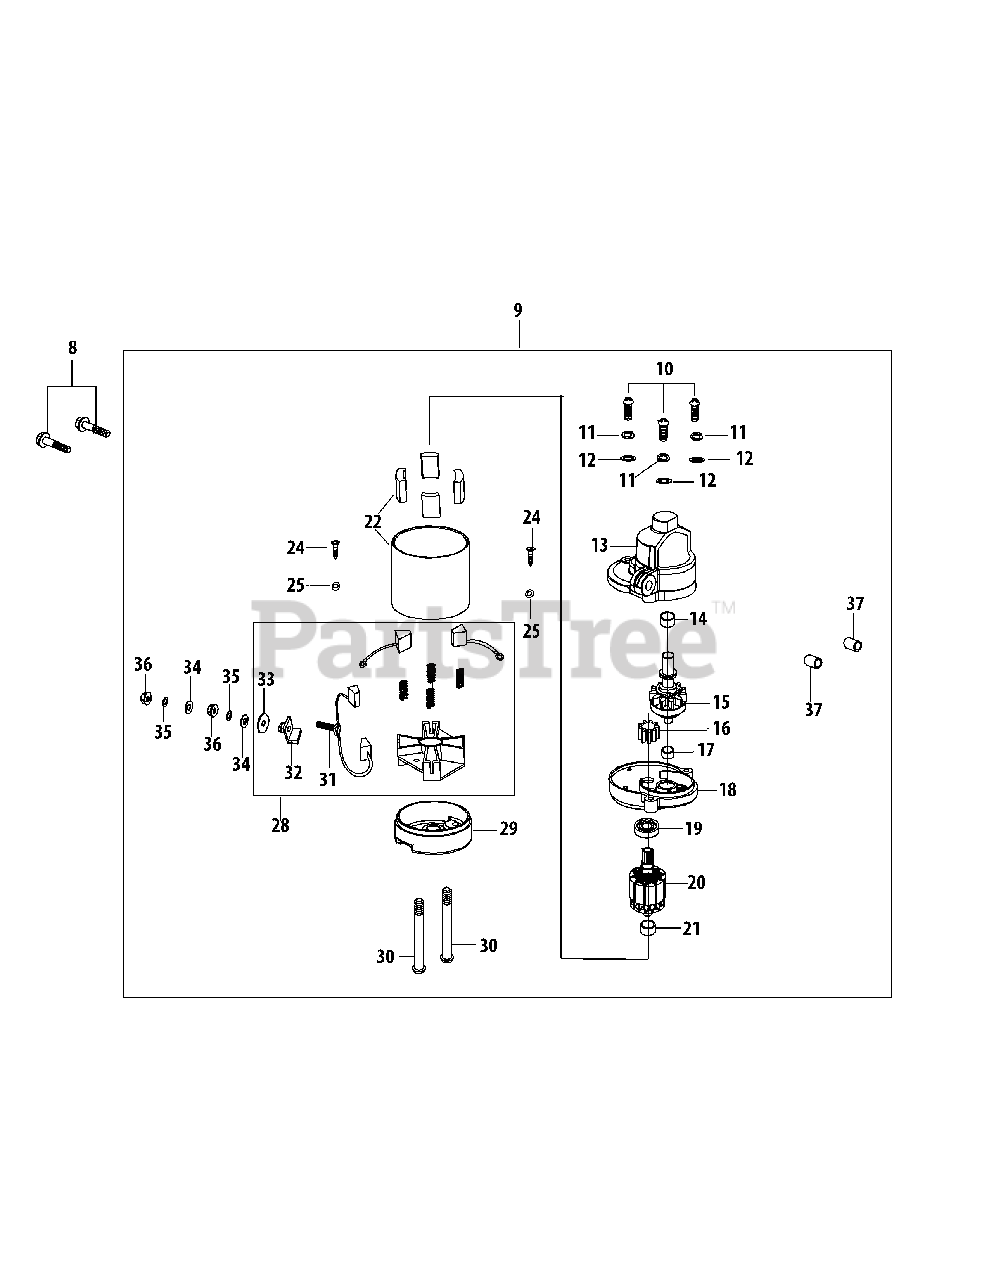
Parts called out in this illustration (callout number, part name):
8	Bolt M8x40
9	Starter Assembly
10	Screw M5x25
11	Lock Washer 5
12	Plain Washer 6
13	Electrical Starter Front Cover
15	Pinion/Clutch Assembly
18	Pinion Cover
19	Bearing 6001Zz
20	Starter Armature
22	Starter Housing Assembly
25	Lock Washer
28	Brush Assembly
29	Electrical Starter Back Cover
30	Bolt M6x100
31	Bolt M6x30 Assembly
32	Waterproof Washer
33	Insulation Washer
34	Plain Washer 6
35	Lock Washer 6
37	Dowel Pin 10x14
